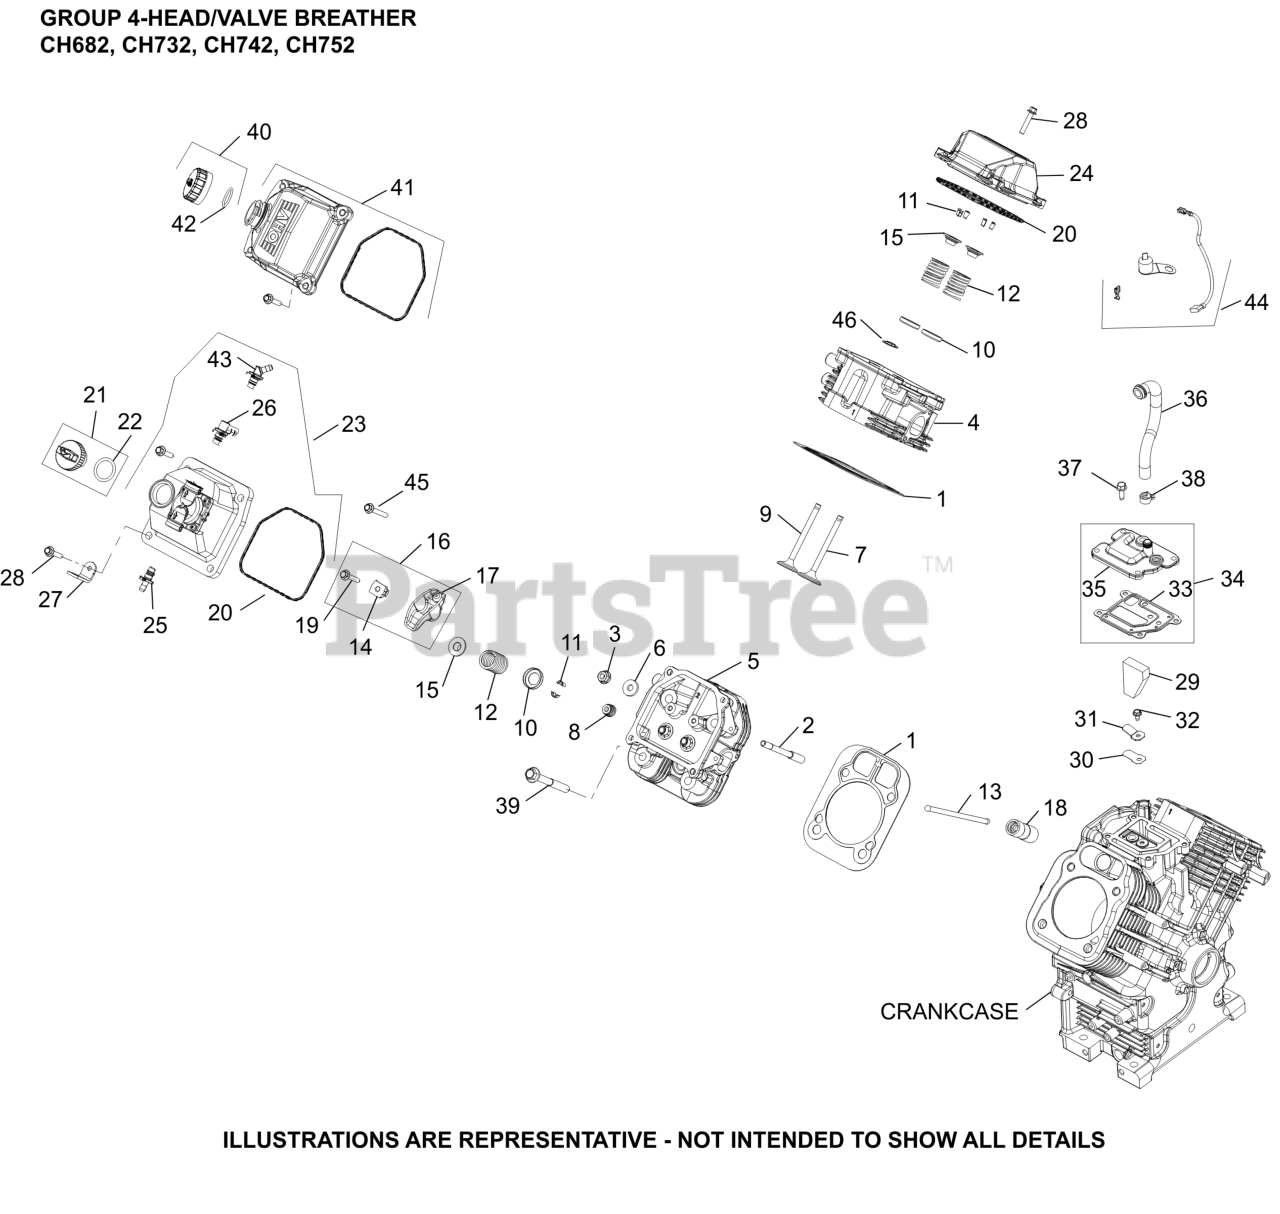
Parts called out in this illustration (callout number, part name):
1	KIT, GASKET CYLINDER HEAD
2	STUD, M8X1.25
3	NUT, FLG M8X1.25
4	KIT, CYLINDER HEAD (#1)-(#2481803S)
5	KIT, CYLINDER HEAD (#2)-(#2481804S)
6	WASHER, FLAT 8.6 MM
7	VALVE, INTAKE (STD)
7	VALVE, INTAKE (.25)
8	SEAL, VALVE BAND
9	VALVE, EXHAUST
9	VALVE, EXHAUST (.25)
10	RETAINER, SPRING
11	KIT, RETAINER
12	SPRING, VALVE
13	ROD, PUSH
14	PIVOT, ROCKER ARM
15	CAP, VALVE SPRING
16	KIT, VALVE TRAIN
17	ARM, ROCKER
18	LIFTER, VALVE HYDRAULIC-USE 25 351 11-S
20	O-RING (YELLOW), VALVE CO
21	CAP ASSY, OIL FILL (YELLOW)
23	KIT,VALVE COVER-FUEL PUMP
24	KIT, VALVE COVER-PLAIN (PLASTIC)
25	KIT, STRAIGHT FITTING
27	STRAP, LIFTING
28	SCREW, FLG M6X1.0X30
29	FILTER, BREATHER
31	RETAINER, REED
32	SCREW, FLG THD FRM M5X.8X10
33	GASKET, BREATHER
35	COVER, BREATHER
36	HOSE, BREATHER (HORIZONTAL)
37	SCREW, THREAD FORMING
43	KIT, 45 DEG. FITTING
46	RETAINER, VALVE GUIDE (KM)
NI	REED, BREATHER
NI	SCREW,HEX FLANGE - USE 25 086 777-S
